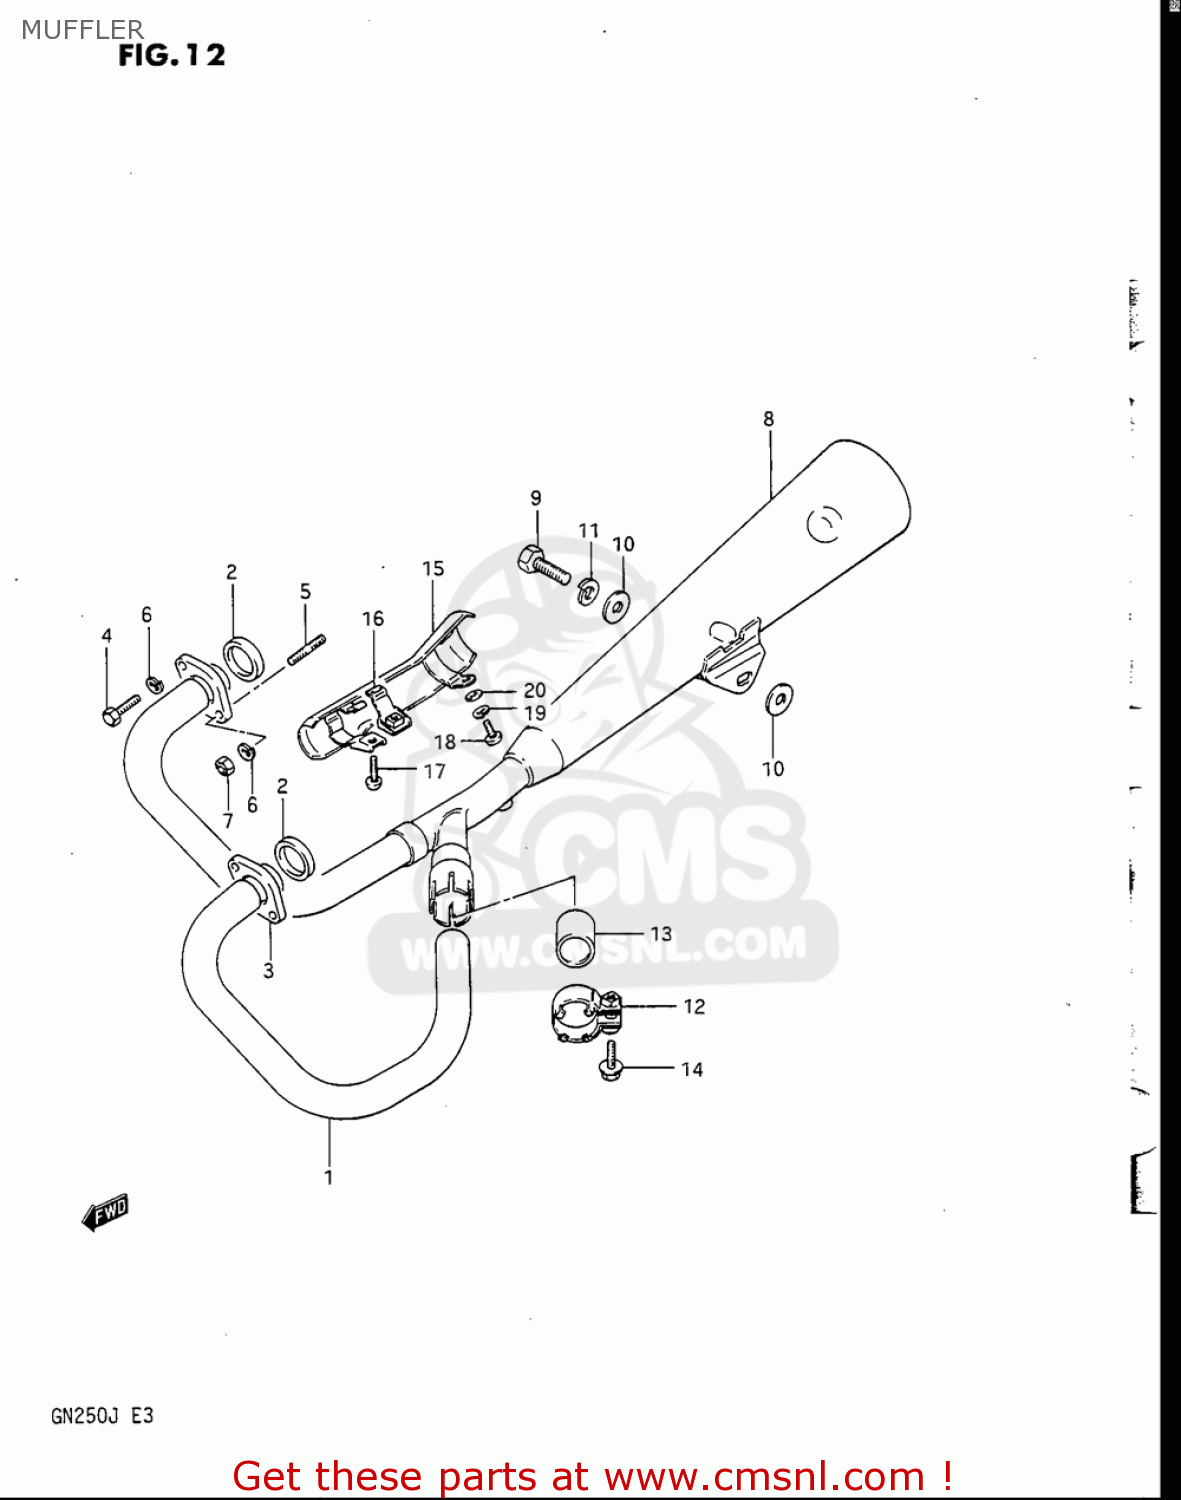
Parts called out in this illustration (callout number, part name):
1	PIPE,EXHAUST,L
2	GASKET,EXHAUST PIPE (NAS)
3	CLAMP
4	BOLT
5	BOLT,STUD
6	WASHER,LOCK
7	NUT
8	BODY,MUFFLER
9	BOLT
10	WASHER
11	WASHER,LOCK
13	CONNECTOR,MUFFLER
14	BOLT
15	COVER,MUFFLER
16	CLAMP,MUFFLER COVER
17	SCREW
18	SCREW
19	WASHER,LOCK
20	WASHER
